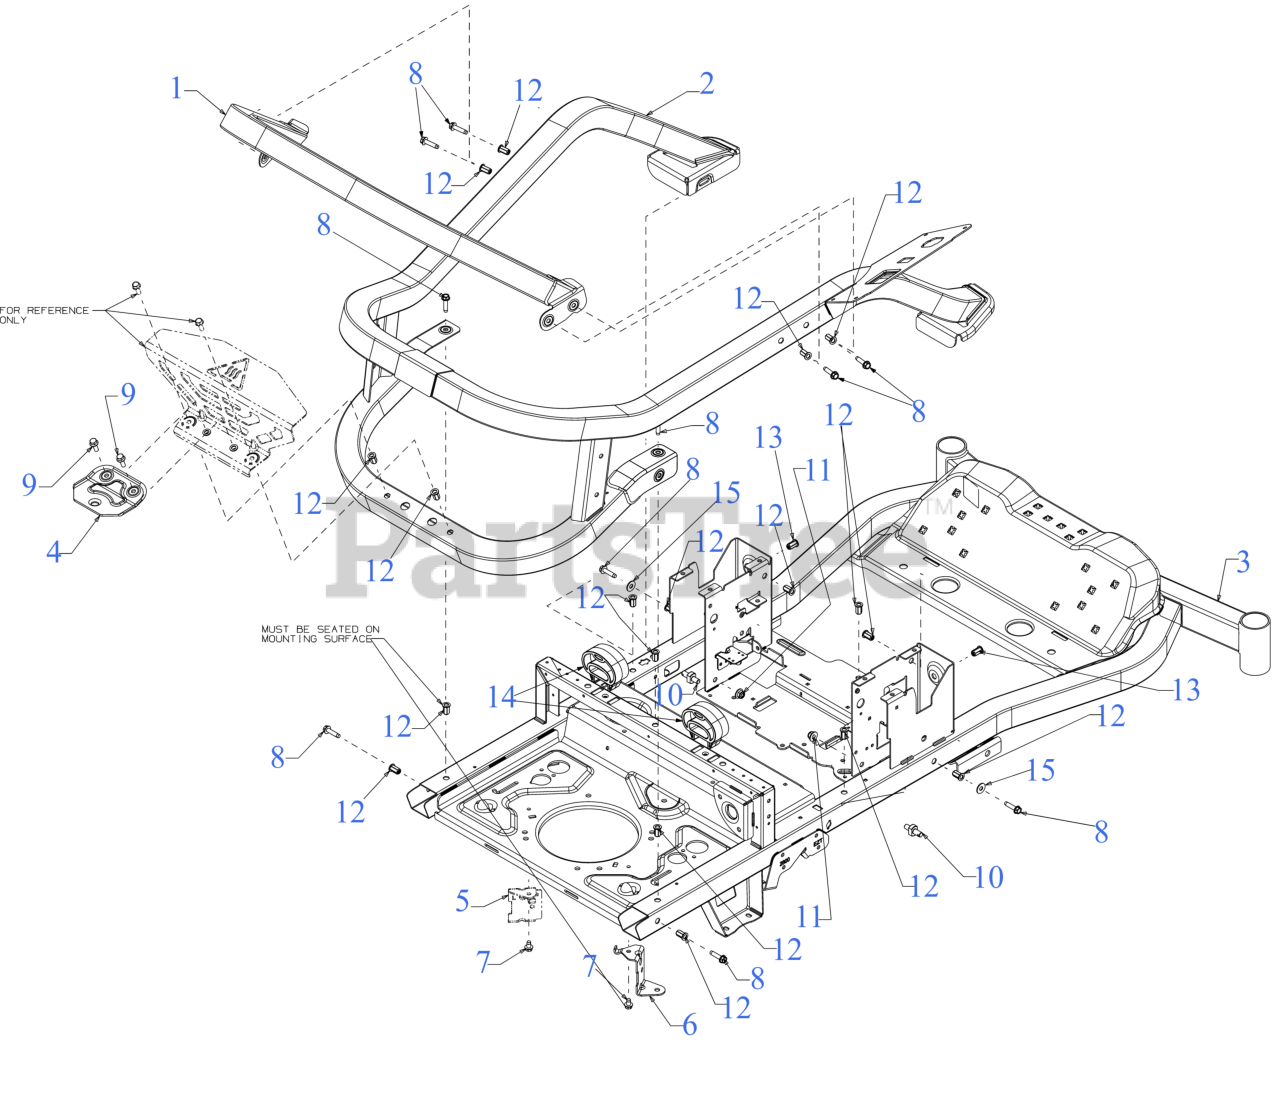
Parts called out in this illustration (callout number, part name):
1	UPPER FRAME HOOP
2	UPPER FRAME
3	FRAME
4	HITCH PLATE
5	TRANSMISSON MOUNT SUPPORT (LH)
6	TRANSMISSON MOUNT SUPPORT (RH)
7	SCREW 5/16-18 x .500
8	SCREW 5/16-18 x 1.25
9	SCREW 5/16-18 x .875 GR5 HXFLG HD
10	SHOULDER STUD
12	NUT RIVET 5/16-18
13	NUT RIVET 5/16-18
14	POLYMER SEAT SPRING
15	FLAT WASHER
